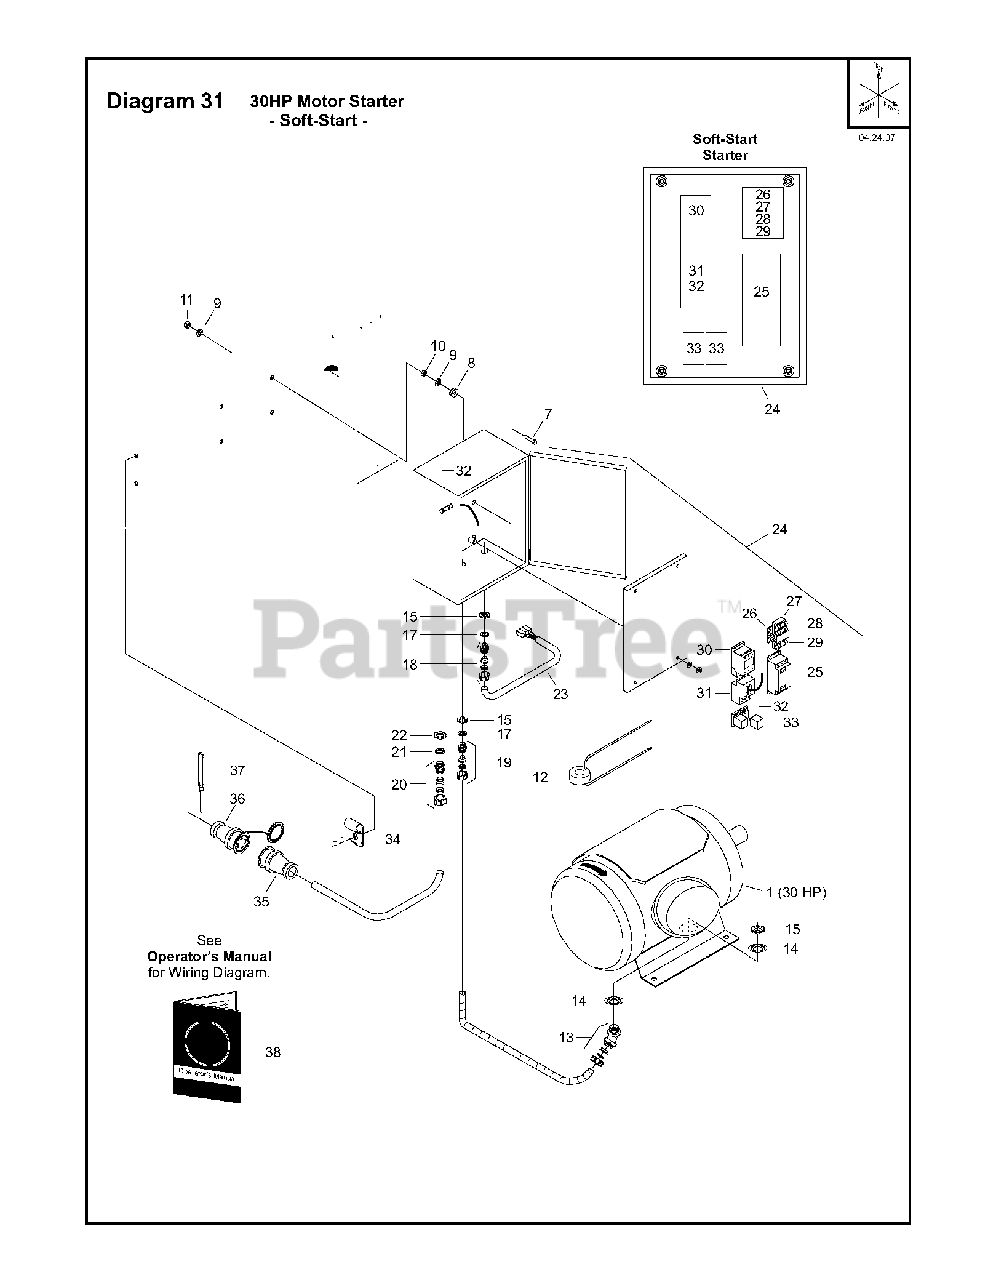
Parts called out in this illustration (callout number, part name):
7	HHCS. M8 X 1.25 X 40 DIN933 ZP
8	GROMMET
9	WASHER
10	NUT
11	LOCKNUT. FIBER M8 DIN 985 Z/P
12	TRNASFORMER: CURRENT
13	CONN: SEAL TIGHT 45 DEG 3/4"
14	REDUCING WASHER. CONDUIT
15	LOCK NUT. 3/4" CONDUIT
18	GRIP.STRT CORD WP .75IN SR-756
20	STRAIN RELIEF. WATER TIGHT 1/2
22	CONDUIT: LOCK NUT 1"
23	CABLE ASSY. CNTRL MTR PRO35III
24	PRO 35 ELECTRIC. SOFT START
25	STARTER
26	SEILZUG RE200A
27	BAR & CHAIN-2159
30	GASSEILZUG 600RDMII
31	OVERLOAD RELAY
32	RESET BUTTON/CABLE
33	CONTROL.THROTL.48.5
36	CONNECTOR. TWIST LOCK 480 VAC
37	CABLE SUPPORT. BUS DROP
